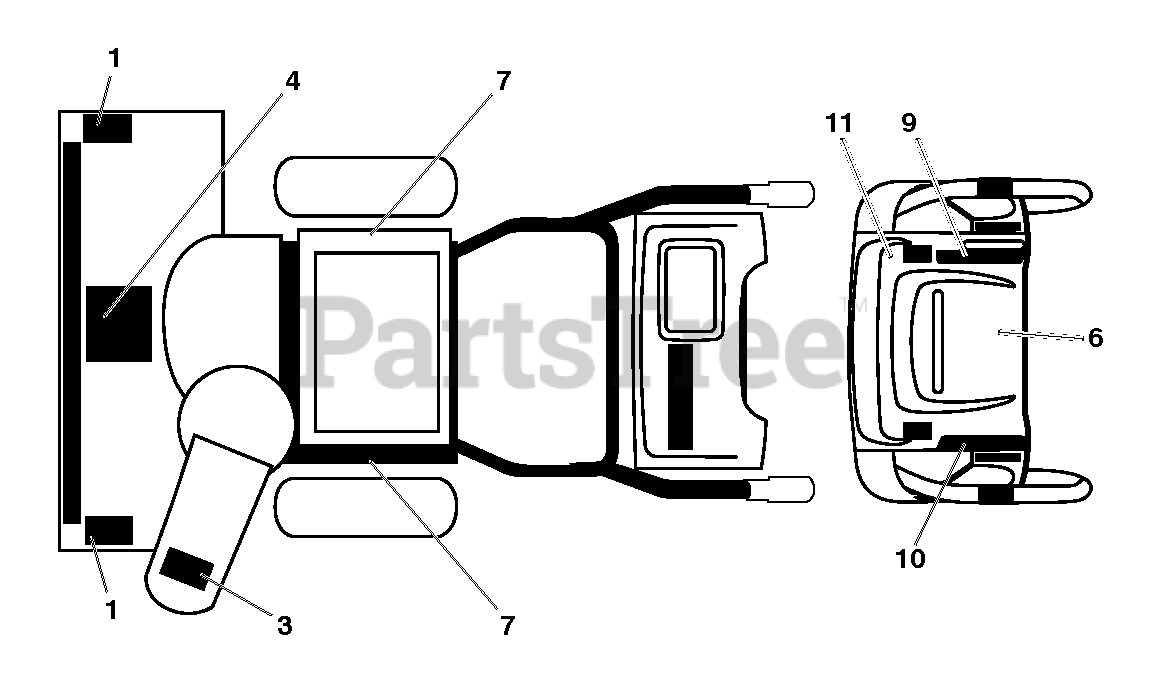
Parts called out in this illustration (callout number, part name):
1	DECAL.AUGER.SAFETY.
3	DECAL.CHUTE.SAFETY.
4	DECAL.AUGER."
7	DECAL.BELT.GUARD.
9	DECAL CONSOLE DECAL DECAL.SNOW
10	DECAL CONSOLE DECAL DECAL.SNOW
11	DECAL.CONSOLE.HAND.WARMER
